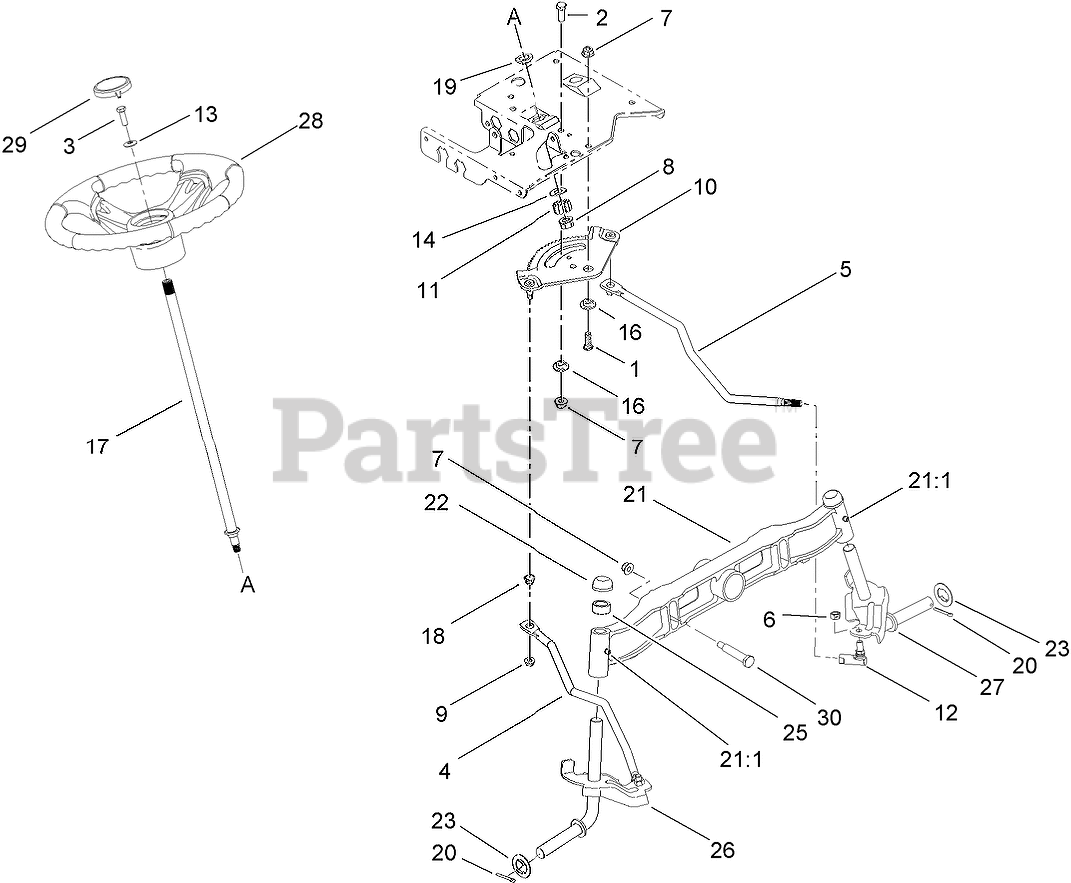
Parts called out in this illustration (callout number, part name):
1	SCREW-HH
2	SCREW-HH
3	SCREW-HH
4	LINK-DRAG, RH
5	LINK-DRAG, LH
6	NUT-HEX, LOCK
7	NUT-LOCK, FLANGE
8	NUT-LOCK, FLANGE
9	NUT-LOCK, FLANGE
10	GEAR-STEERING
11	GEAR-PINION, STEERING
12	BALL JOINT ASM
13	WASHER-FLAT
14	WASHER-FLAT
16	SPACER-SHOULDER
17	SHAFT-STEERING
18	BUSHING
19	BEARING-FLANGE, HEX
20	PIN-COTTER
21	PIVOT-AXLE, CAST IRON
21:1	FITTING-GREASE
23	WASHER-FLAT
25	SPACER
26	RH AXLE ASM
27	LH AXLE ASM
28	3 SPOKE WHEEL STEERING ASM
29	CAP-WHEEL, STEERING
30	BOLT-SHOULDER
